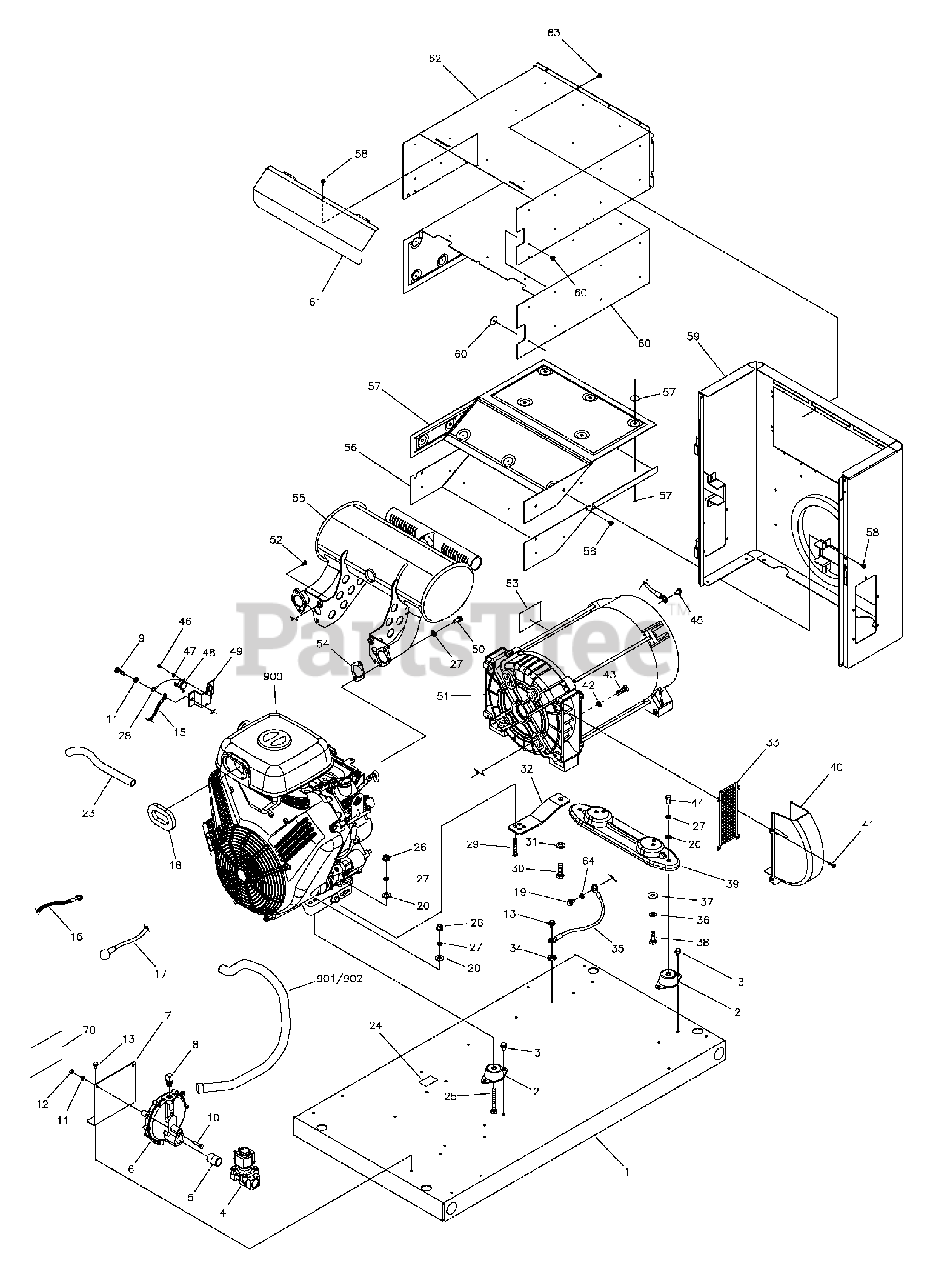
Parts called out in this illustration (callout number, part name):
2	MOUNT, Vibration
4	SOLENOID, Gas Fuel
6	REGULATOR, NG / LPG
7	BRACKET
9	*CAPSCREW, Hex Head, M6 - 1 x 16
10	*CAPSCREW, Hex Head, M6 - 1 x 30
11	*WASHER, Lock, 1/4
12	*NUT, M6 - 1
13	BOLT
18	TUBE
20	*WASHER, Flat, 5/16 - M8
23	HOSE, Oil Drain
24	DECAL
25	*CAPSCREW, Hex Head, Full Thread, 5/16-18 x 2-1/2
26	*NUT, 5/16-18
27	*WASHER, Lock, 5/16 - M8
29	*CAPSCREW, Hex Head, 5/16-18 x 2
30	*CAPSCREW, Hex Head, M12 - 1-3/4 x 35
31	*WASHER, M12
32	SUPPORT, Engine
34	*WASHER, Shakeproof, EXT M6 - 1/4
36	*WASHER, Lock, 3/8
37	*WASHER, Flat, 3/8 - M10
38	*CAPSCREW, Hex Head, 3/8-16 x 1
39	BRACKET, Alternator
41	*SCREW, Taptite, M5.8 x 10
42	*WASHER, Lock, 3/8
43	*CAPSCREW, 3/8-16 x 1-1/4
44	*CAPSCREW, Hex Head, 5/16-18 x 3/4
45	BOLT
46	*SCREW, Phillips Head, 4-40 x 0.19
47	*WASHER, Lock, #4
48	SWITCH, Temp
49	PLATE, Temp Switch
50	SCREW
51	ALTERNATOR ASSEMBLY
59	BULKHEAD, Alternator
62	BOX, Muffler Top
64	*WASHER, Shakeproof, M6
70	DECAL, Fuel Requirements
900	**ENGINE
901	FUEL HOSE
